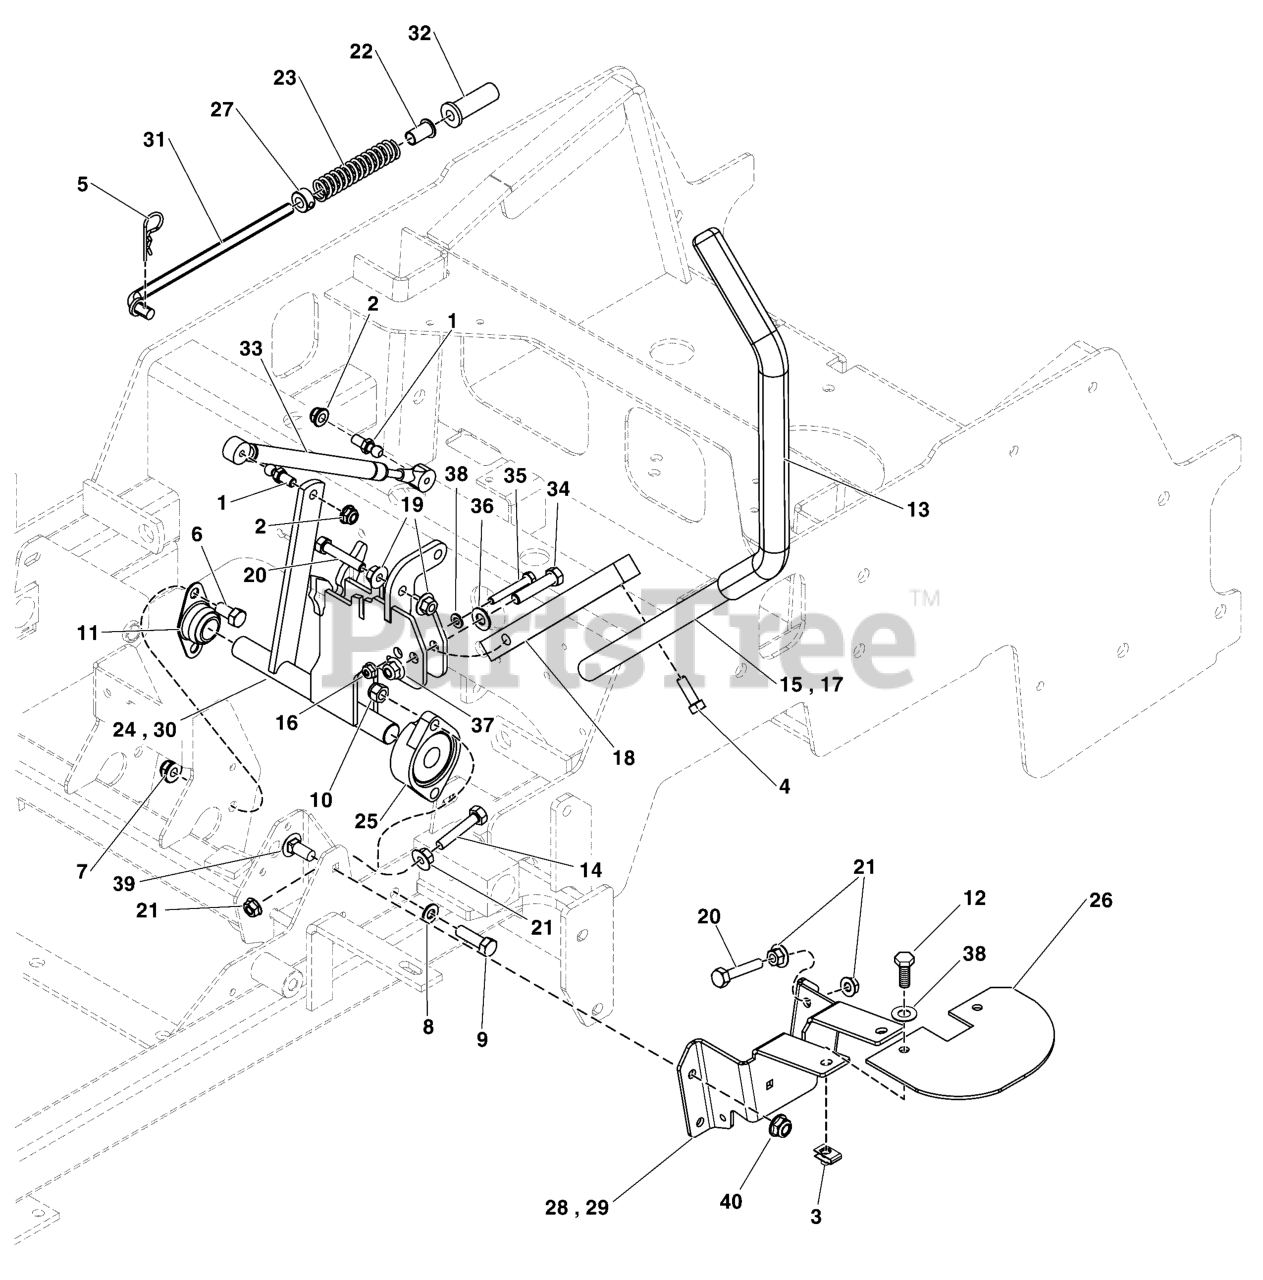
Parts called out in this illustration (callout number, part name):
1	10MM BALL STUD, 5/16-18 X 3/4 THDS
2	NUT, Flange Nylock, 5/16-18
3	BODY CLIP, 1/4-20 X 1/2" DEEP
4	SCREW, Flange, Whiz-Lock, 5/16-18 X 3/4
5	PIN, HAIR, .0915 X 1-7/8
6	CAPSCREW, Hex Head, 3/8-16 x 3/4
7	NUT, Hex Flange, Nylock, 3/8-16
8	WASHER, Flat, 5/16
9	BOLT, 3/8-16 X 1-1/4 SHCS (SOCKET HEAD)
10	NUT, Hex, Nylon Lock, 3/8-16
11	BEARING, Flange, Bronze, 3/4"
12	CAPSCREW, Hex Head, 1/4-20 x 3/4 (stiffener to top of cover)
13	GRIP, FOAM, 1" ID, 16" LONG
14	BOLT, 5/16-18 x 1-1/4" TFL GD 5
15	CONTROL, Handle
16	NUT, Flange Nylock , 1/4-20
17	CONTROL, Handle
18	MOUNT, CONTROL ARM
19	NUT, 5/16-18 HEX SERRATED FLANGE (LARGE)
20	CAPSCREW, Hex Head, Flange Lock Taptite, 5/16-18 X 1-3/4
21	NUT, Hex Serrated Flange, 5/16-18,
22	BUSHING, FLANGE 3/8ID X 7/8 LONG
23	SPRING, REVERSE RETURN
24	WELD, CONTROL SHAFT, LOCKOUT, LH - BLK
25	BEARING, FLANGE
26	PLATE, NUETRAL LOCK SHIELD, IS700 - BLK
27	COLLAR, 3/8" SET
28	PLATE, NEUTRAL LOCK, LH - BLK
29	PLATE, NEUTRAL LOCK, RH - BLK
30	WELD, CONTROL SHAFT, LOCKOUT, RH - BLK
31	ROD, NEUTRAL RETURN, CZ
32	FLANGED BUSHING, 3/8IDX.63ODX.8125FL
33	DAMPENER, CONTROL, #(P6709/P3610)
34	CAPSCREW, Hex Head, 3/8-16 X 1-3/4
35	CAPSCREW, Hex Head, 1/4-20 X 1-3/4
36	WASHER, .406
37	NUT, Hex Flange, 3/8-16
38	WASHER, Flat, 1/4
39	BOLT, 5/16-18 X 3/4, CARRIAGE, GD5, CZ
40	NUT, 5/16-24, Hex, GR5, Zinc/Clear
